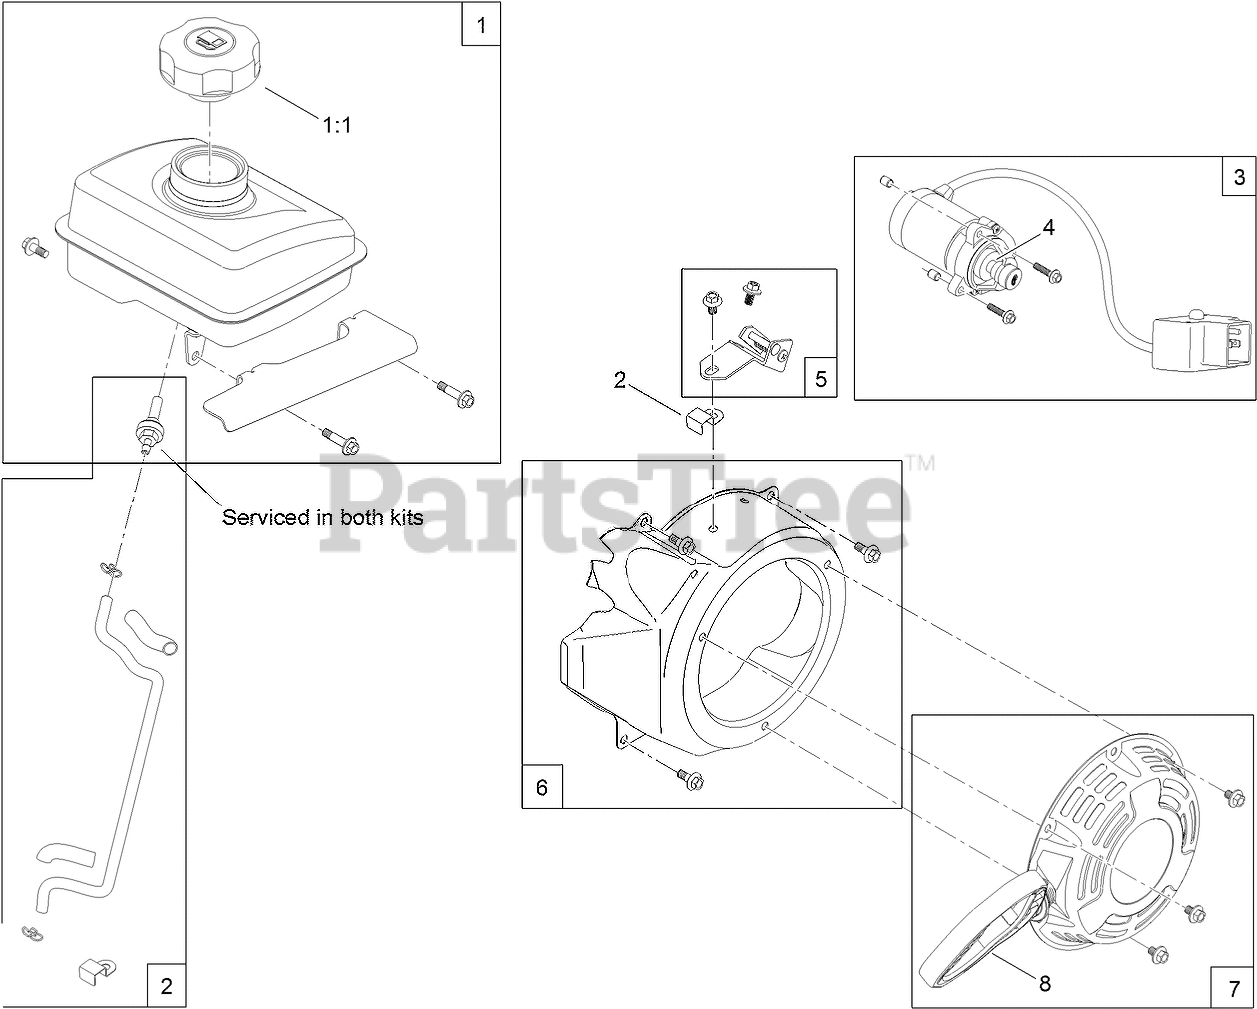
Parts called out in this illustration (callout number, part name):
1	FUEL TANK AND CAP KIT
1:1	CAP-FUEL
2	FUEL LINE KIT
3	ELECTRIC STARTER KIT
4	PINION KIT
5	GOVERNOR KIT
6	BLOWER SHROUD KIT
7	RECOIL ASM KIT
8	MITTEN GRIP KIT
